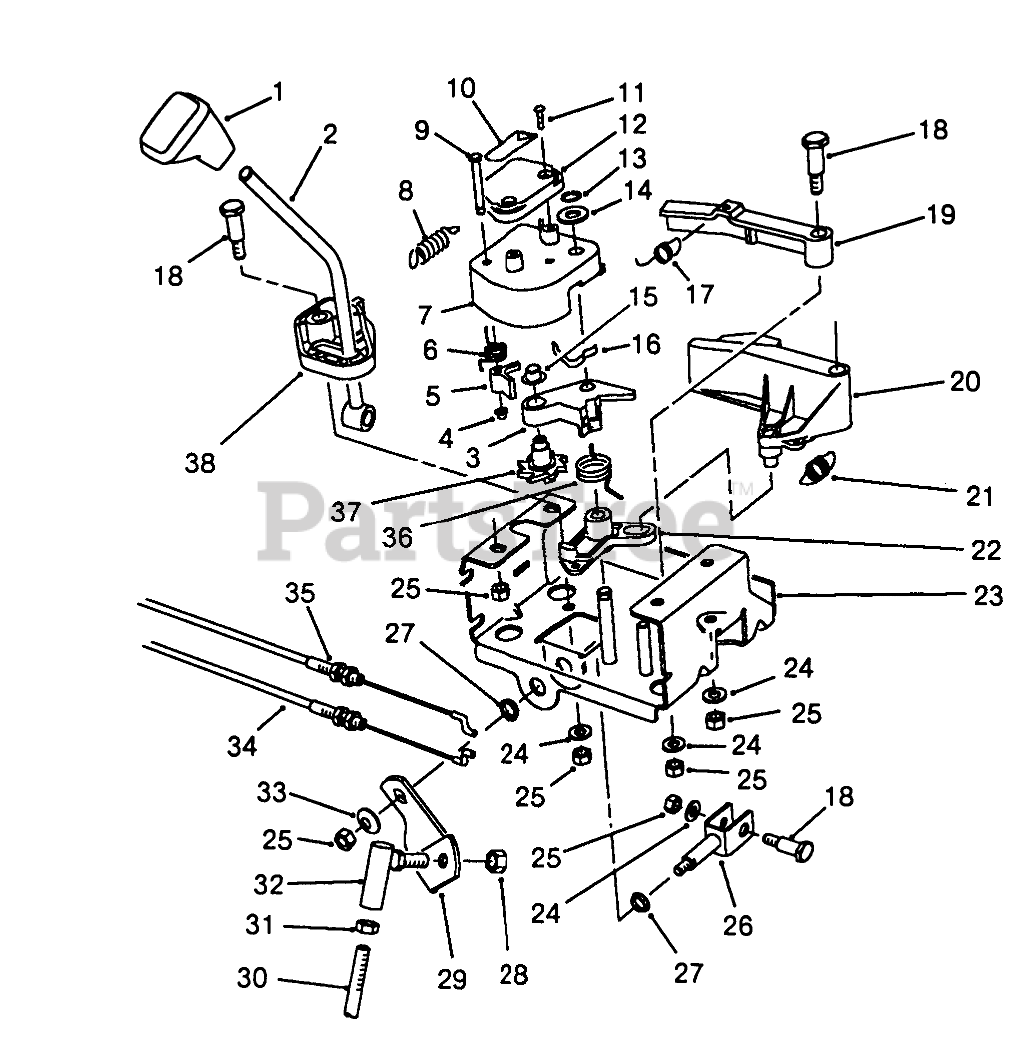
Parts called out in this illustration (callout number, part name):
1	KNOB-SHIFT
2	SHIFT ROD WA
3	LEVER-WHEEL, INDEX
4	NUT-PUSH
5	TANG-INDEX
6	SPRING-TORSION
7	LATCH-LEVER
8	SPRING-EXTENSION
9	PIN-TANG
10	DECAL
11	SCREW-PPH
12	COVER-LATCH
13	RING-RETAINING
14	WASHER-THRUST
15	RETAINER-PUSH ON
16	SPRING-FLAT
17	SPRING-EXTENSION
18	SCREW-SHOULDER
19	LEVER-LOCKOUT
20	LEVER-REVERSE
21	SPRING-EXTENSION
22	LEVER-REVERSE, SWITCH
23	Frame-Control
24	WASHER-PLAIN
25	NUT-LOCK, NI
26	CLEVIS WA
27	BUSHING
28	NUT-LOCK
29	BRACKET-SHIFT
30	ROD-BENT SHIFT, LOWER
31	NUT-HJ
32	JOINT-BALL
33	WASHER-BELLEVILLE
34	CABLE-GEARBOX
35	CABLE-ARM, LATCH
36	SPRING-TORSION
37	WHEEL-INDEX
38	BASE-LOCKOUT
